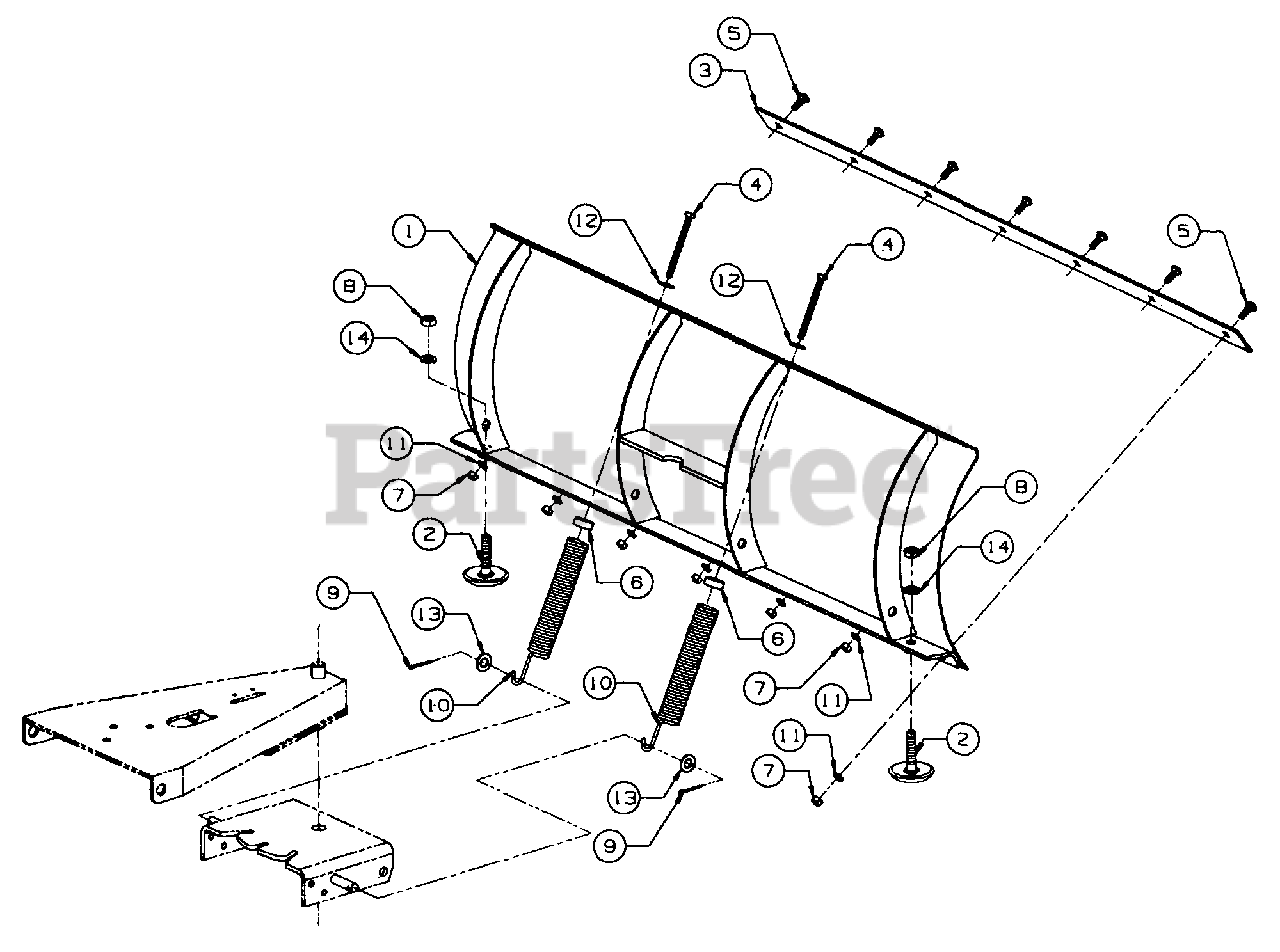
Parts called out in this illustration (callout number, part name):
1	Blade, 42" Dozer
1	Graphic, Cub Cadet
2	Shoe, Skid
3	Blade, Cutting Edge
4	Screw, Hex Cap, 5/16-18 X 3.50 Lg
5	Bolt, Sht Nk Carriage, 5/16-18 X .875 Lg
6	Insert, Spring
7	Nut, Hex, 5/16-18 GR5
8	Nut, Hex Jam, 1/2-13 GR5
9	Pin, Cotter, 1/8 Dia X 1.25 Lg
10	Spring, Extension, 1.25 Dia X 6.0 Lg
11	Washer, Lock, 5/16
12	Washer, Flat, .349 X .879 X .063 Thk
13	Washer, Flat, .510 X 1.0 X .06 Thk
14	Washer, Lock, 1/2
